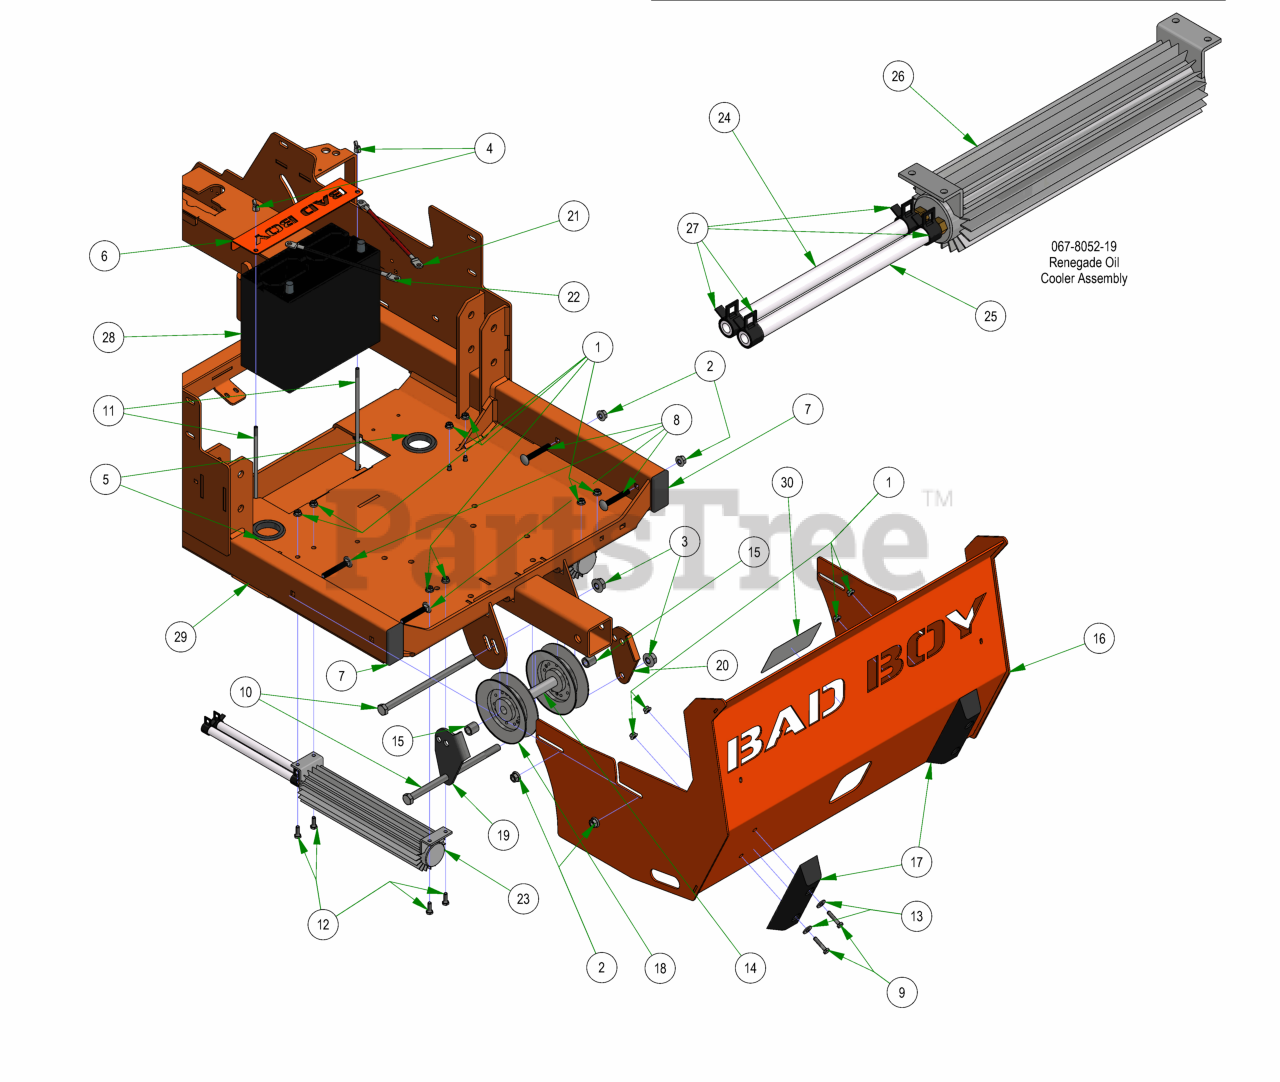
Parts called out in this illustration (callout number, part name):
1	1/4-20 NYL INSERT FLANGE LOCKNUT ZINC
2	3/8-16 NYLON INSERT FLANGE LOCKNUT (GR.F) ZINC
3	1/2-13 NYLON INSERT FLANGE LOCKNUT ZINC
4	1/4-20 WING NUT FORGED (TYPE A) LIGHT SERIES ZINC
5	2019 2" x .25 Rubber Grommet
6	2019 Horizontal Battery Hold Down Cover
7	1 1/2 x 3 Frame Plug
8	3/8" x 2 1/2" Carriage Bolt
9	1/4-20 X 1-1/4 HEX CAP SCREW (GR.5) ZINC
10	1/2-13 X 9 HEX CAP SCREW (GR.5) ZINC
11	1/4-20 X 9 CARRIAGE BOLT ZINC
12	1/4-20 X 3/4 HEX CAP SCREW (GR.5) ZINC
13	1/4 USS FLAT WASHER (3/4 OD) ZINC
14	2019 Pulley Spacer .75 x .5 x 4.375
15	.51 ID X .75 OD X .75 LGTH SOLID SPACER ZINC
16	2019 Horizontal Suspension Rear Cover
17	8" Rubber Bumper
18	2019 Outlaw Horizontal Rear V Pulley
19	Renegade Deck Belt Rear Keeper - Left
20	Renegade Deck Belt Rear Keeper-Right
21	Red Battery Cable - Diesel
22	Black Battery Cable - Diesel
23	Renegade Oil Cooler Assembly
24	3/8" Clear Hose - 14"
25	3/8" Clear Hose - 24"
26	2019 12" Oil Cooler With Fittings
27	3/8" Hose Clamp
28	Battery - Diesel/Renegade Models PF-516
29	2019 Renegade Gas Frame - Powdercoated
30	2019 Renegade Pump Belt Route Decal
